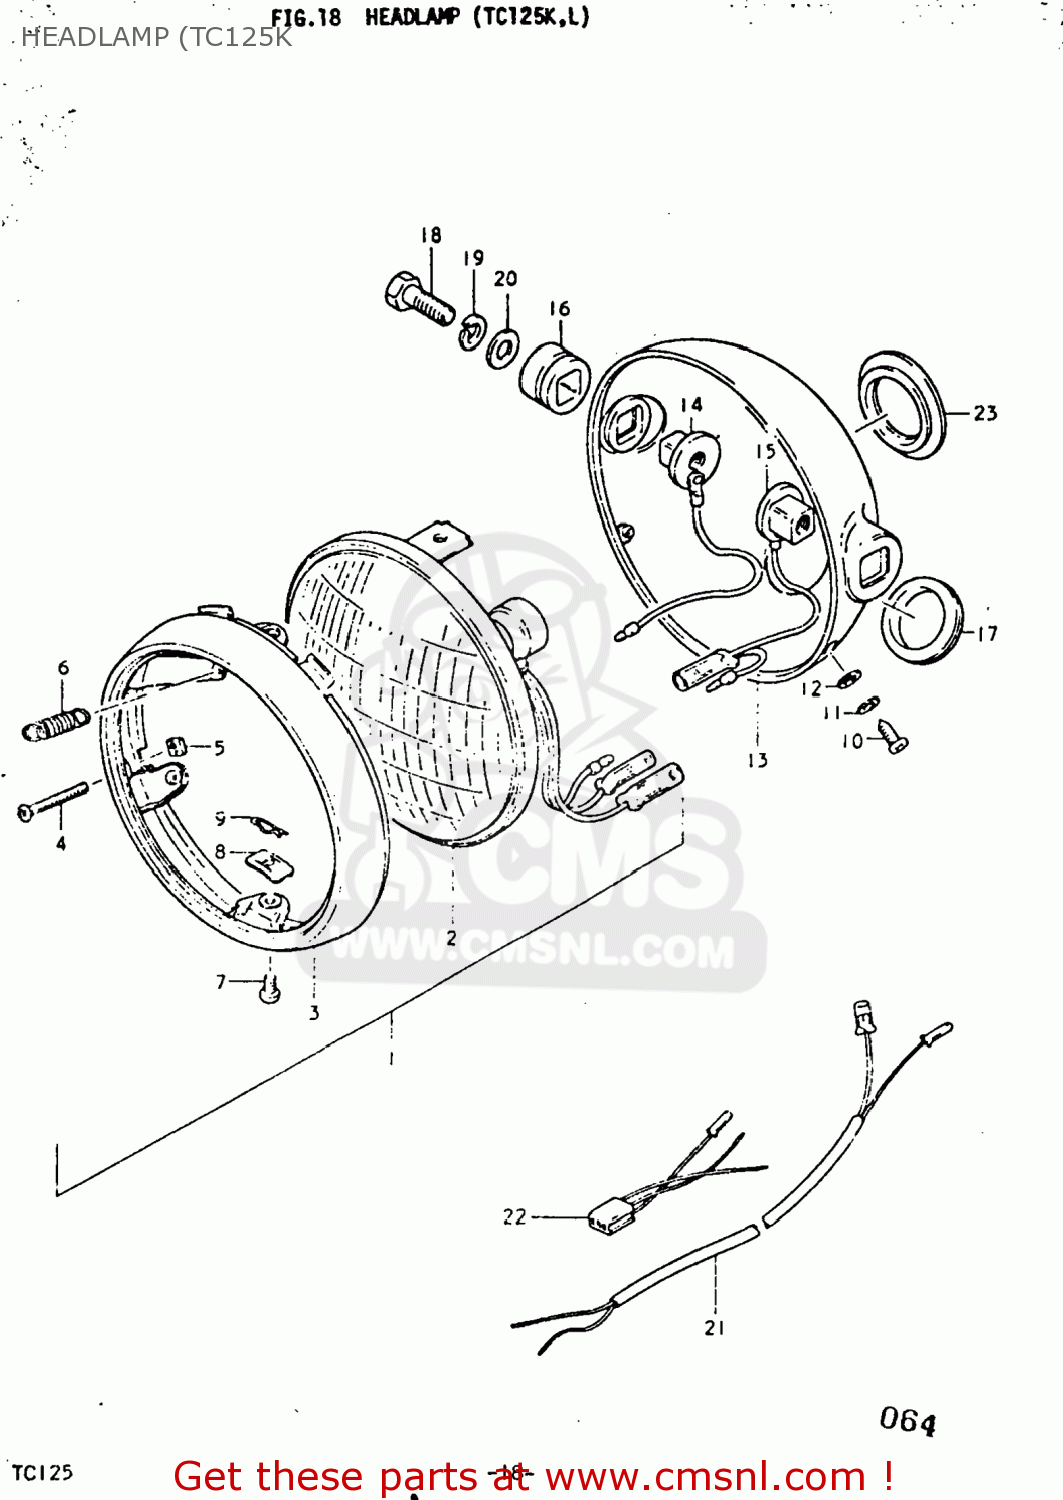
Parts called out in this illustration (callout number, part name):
1	HEADLAMP ASSEMBLY
2	LAMP UNIT
3	RIM,HEADLAMP
4	SCREW,HEADLAMP ADJUST
5	NUT,HEADLAMP ADJUSTER
6	SPRING,HEADLAMP ADJUST
7	SCREW,LENS
8	NUT,ADJUSTING
9	CUSHION,HEADLAMP
10	SCREW
12	WASHER
13	HOUSING,HEADLAMP
14	SPACER,HEADLAMP HOUSING
15	SPACER,HEADLAMP HOUSING
16	CUSHION,HEADLAMP HOUSING
17	GROMMET,HEADLAMP HOUSING
18	BOLT
19	LOCK WASHER
20	WASHER
21	WIRE
22	WIRE
23	CAP
